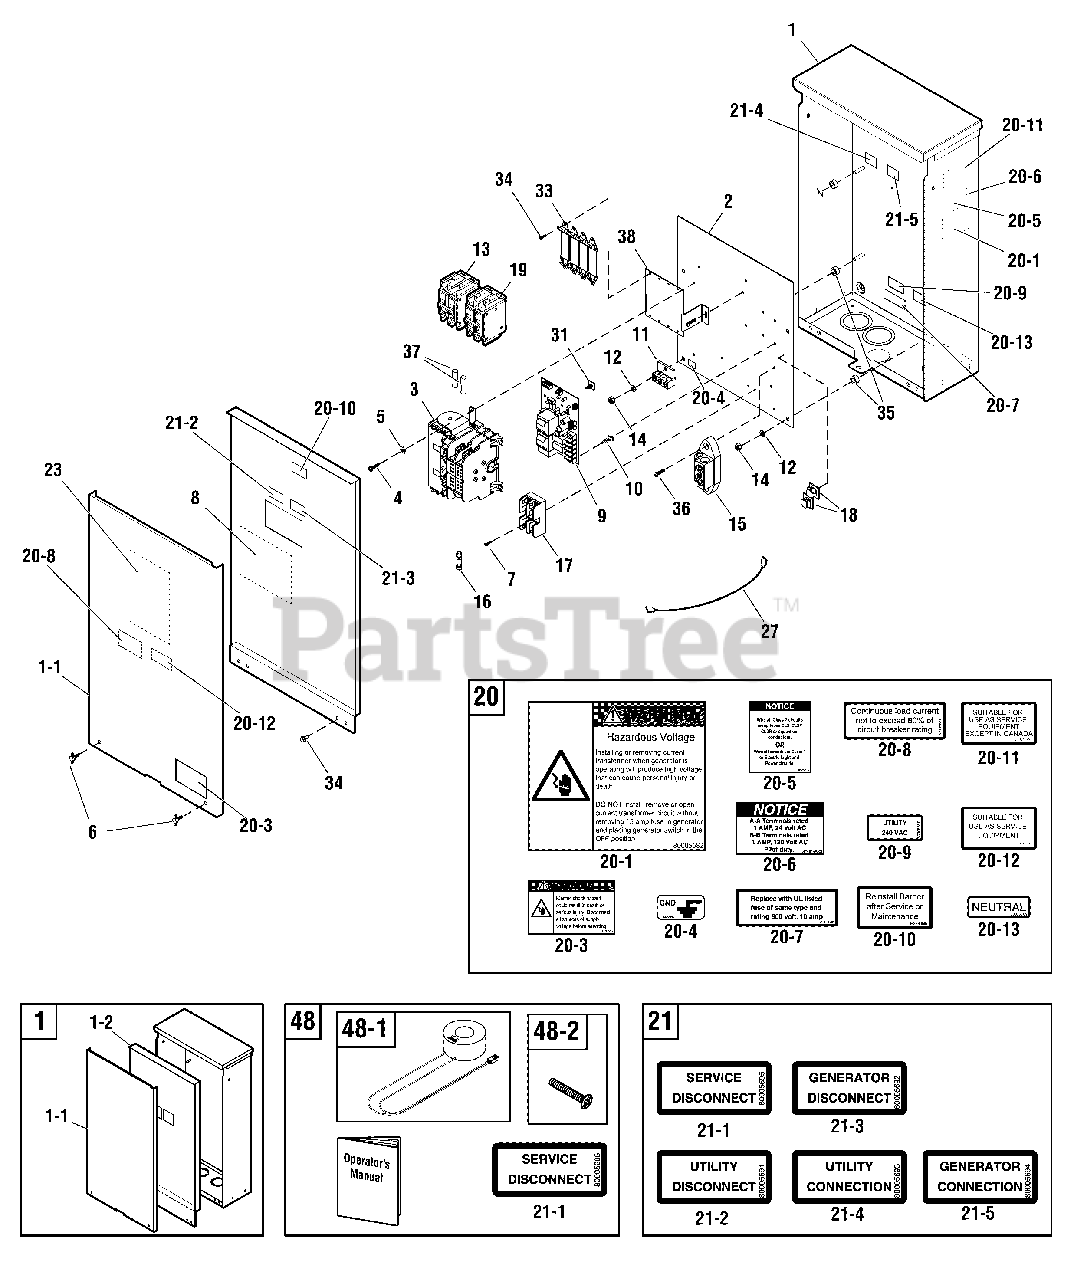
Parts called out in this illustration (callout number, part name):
1	ENCLOSURE
2	BACK PANEL
3	SWITCH, Transfer
4	* SCREW, Hex Head, Trilobular, #10-32 x 1/2
5	* WASHER-EXT. #10
7	* SCREW, Hex Head, Trilobular, #6-32 x 3/8
8	INSULATION, Dead Front
9	BOARD, Circuit
10	SPACER, PCB Board, 1/2
11	LUG
12	* WASHER, Lock, 1/4
13	BREAKER, Circuit, 100A
14	* NUT, 1/4-20
15	TERMINAL, Neutral
18	CLIP, Latching Wire
19	BREAKER, Circuit, 100A
20	DECAL SHEET - WARNINGS
20-1	DECAL, Warning Voltage
20-3	DECAL, Warning Shock
20-4	DECAL, Ground
20-5	DECAL, Notice
20-6	DECAL, Contacts Rated
20-7	DECAL, Fuse, 10 Amp
20-8	DECAL, Breaker, Circuit
20-9	DECAL, Sensing, Utility
20-10	DECAL, Reinstall After
20-11	DECAL, Not Suitable
20-12	DECAL, Suit. as Service Equip.
20-13	DECAL, Neutral
21	DECAL SHEET-CONNECTIONS
21-2	DECAL, Disconnect Utility
21-3	DECAL, Gen Disconnect
21-4	DECAL, Connection, Utility
21-5	DECAL, Connect Gen
34	* SCREW, Hex Head, Trilobular, 8-32 x 3/8
35	SPACER
36	* SCREW, Hex Head, Trilobular, #10-32 x 3/4
48	KIT, Manual/ACC
48-1	CURRENT TRANSFORMER
